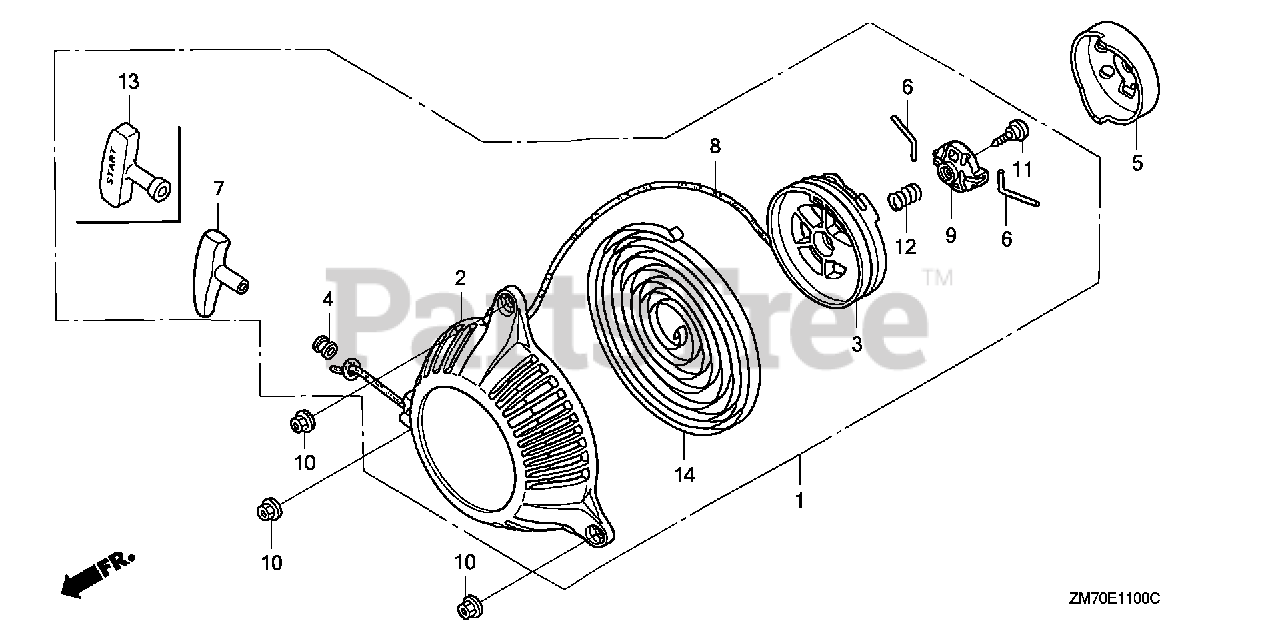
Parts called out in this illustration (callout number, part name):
1	STARTER ASSY., RECOIL
2	CASE, RECOIL STARTER
3	REEL, RECOIL STARTER
4	GUIDE, ROPE
5	PULLEY, RECOIL STARTER
7	KNOB, RECOIL STARTER
8	ROPE, RECOIL STARTER
10	NUT, FLANGE (5MM)
11	SCREW, SETTING
12	SPRING, FRICTION
14	SPRING, RECOIL STARTER
